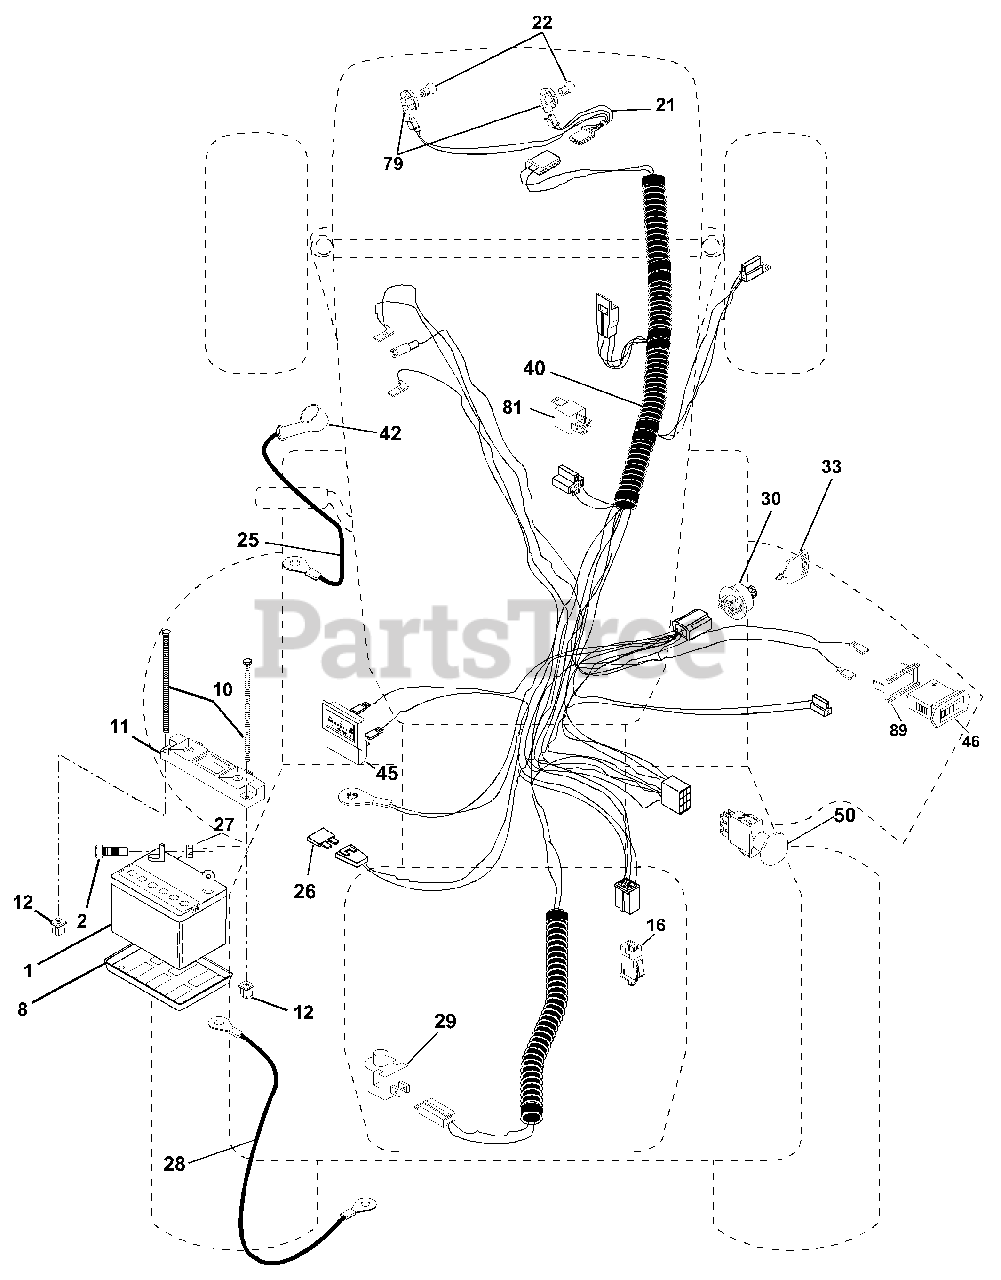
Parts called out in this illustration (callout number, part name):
1	Battery
2	Bolt Hex Head 1/4-20 x 3/4
8	Tray, Battery
10	Bolt, Battery Front 1/4-20 x 7.5 Zinc
11	Holddown Battery Front Mount
12	Nut, Push Nylon 1.4" Battery Front
16	Switch Interlock Push-In
21	Harness Socket Light w/4152J
22	Bulb Light
25	Cable, Battery
27	Nut Keps Hex 1/4-20
28	Cable,Ground
29	Switch, Plunger Normal Op Olive
30	Switch, Ign
40	Harness Ign.
42	Cover, Terminal Red
46	Hourmeter Snap-In
50	Switch, PTO
79	Bulbholder Asm
81	Relay Asm.
89	Bracket Snap-In Hourmeter
